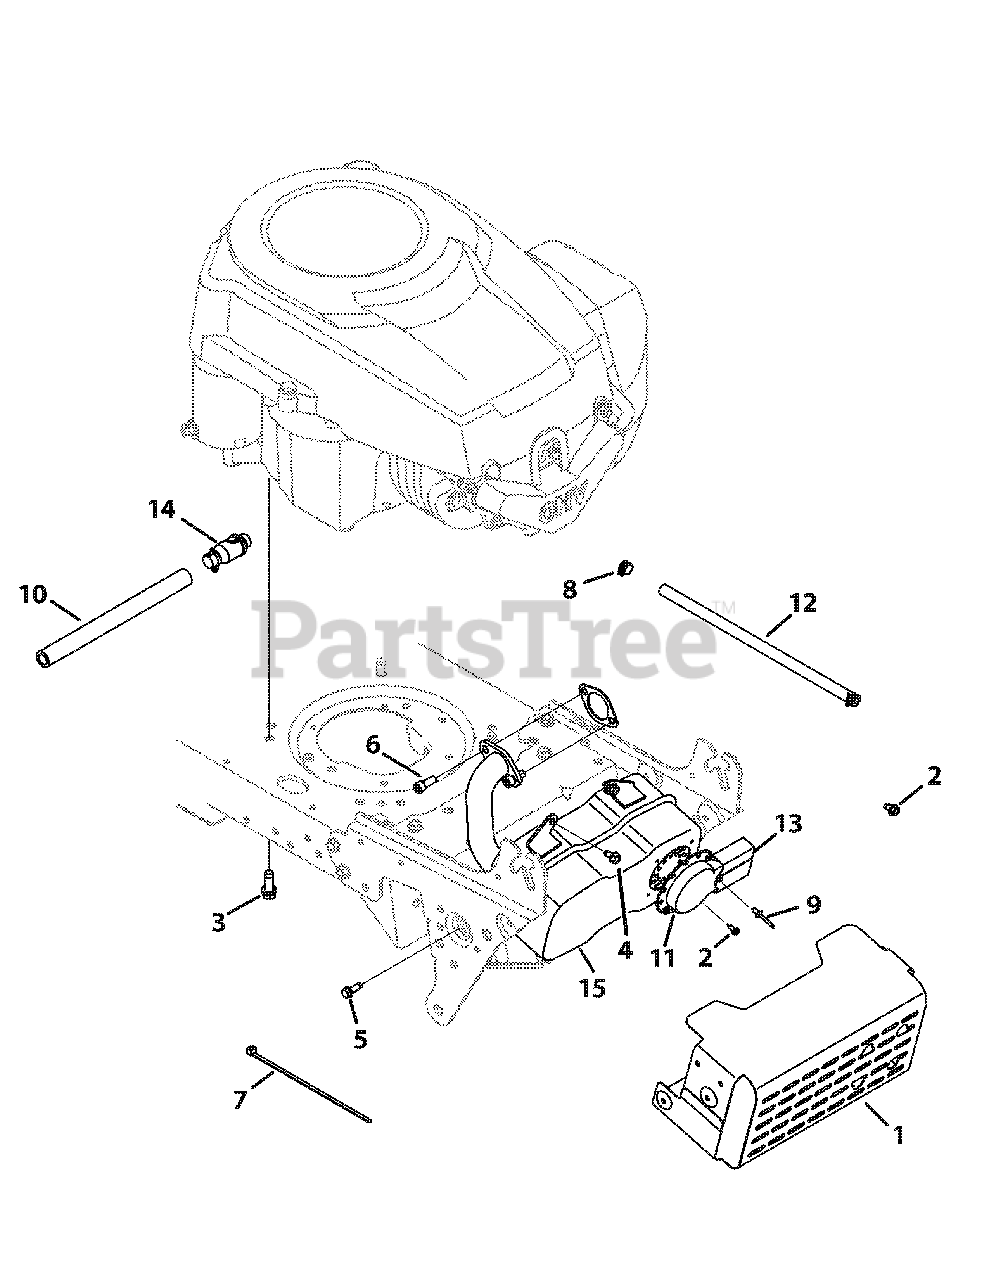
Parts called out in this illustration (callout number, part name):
1	Muffler Shield Assembly
2	Hex AB Scr #8-18 x .50
3	TT Screw 3/8-16 x 1.00
4	Hex Wash S-Tapp Scr 1/4-20 x .50
5	Thd Forming Scr. 1/4-20 x .75 Lg.
6	Scr. 5/16-18 x .75
10	Extension Hose, Oil Drain
11	Muffler Deflector
13	Long Muffler Deflector
15	Muffler
